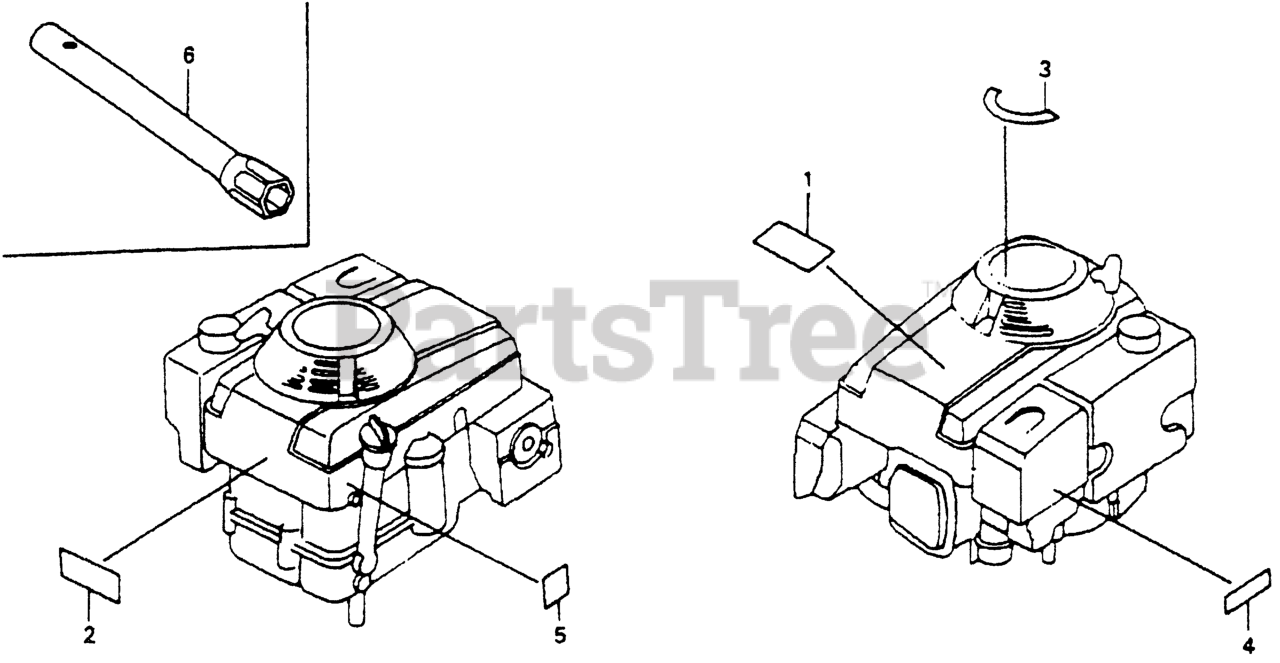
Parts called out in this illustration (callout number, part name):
1	EMBLEM, TOP COVER
2	LABEL, EMBLEM (H)
3	MARK, EASY START (ENGLISH)
4	MARK, AIR CLEANER CAUTION
5	MARK, OIL CAUTION
6	WRENCH, BOX (P21)
